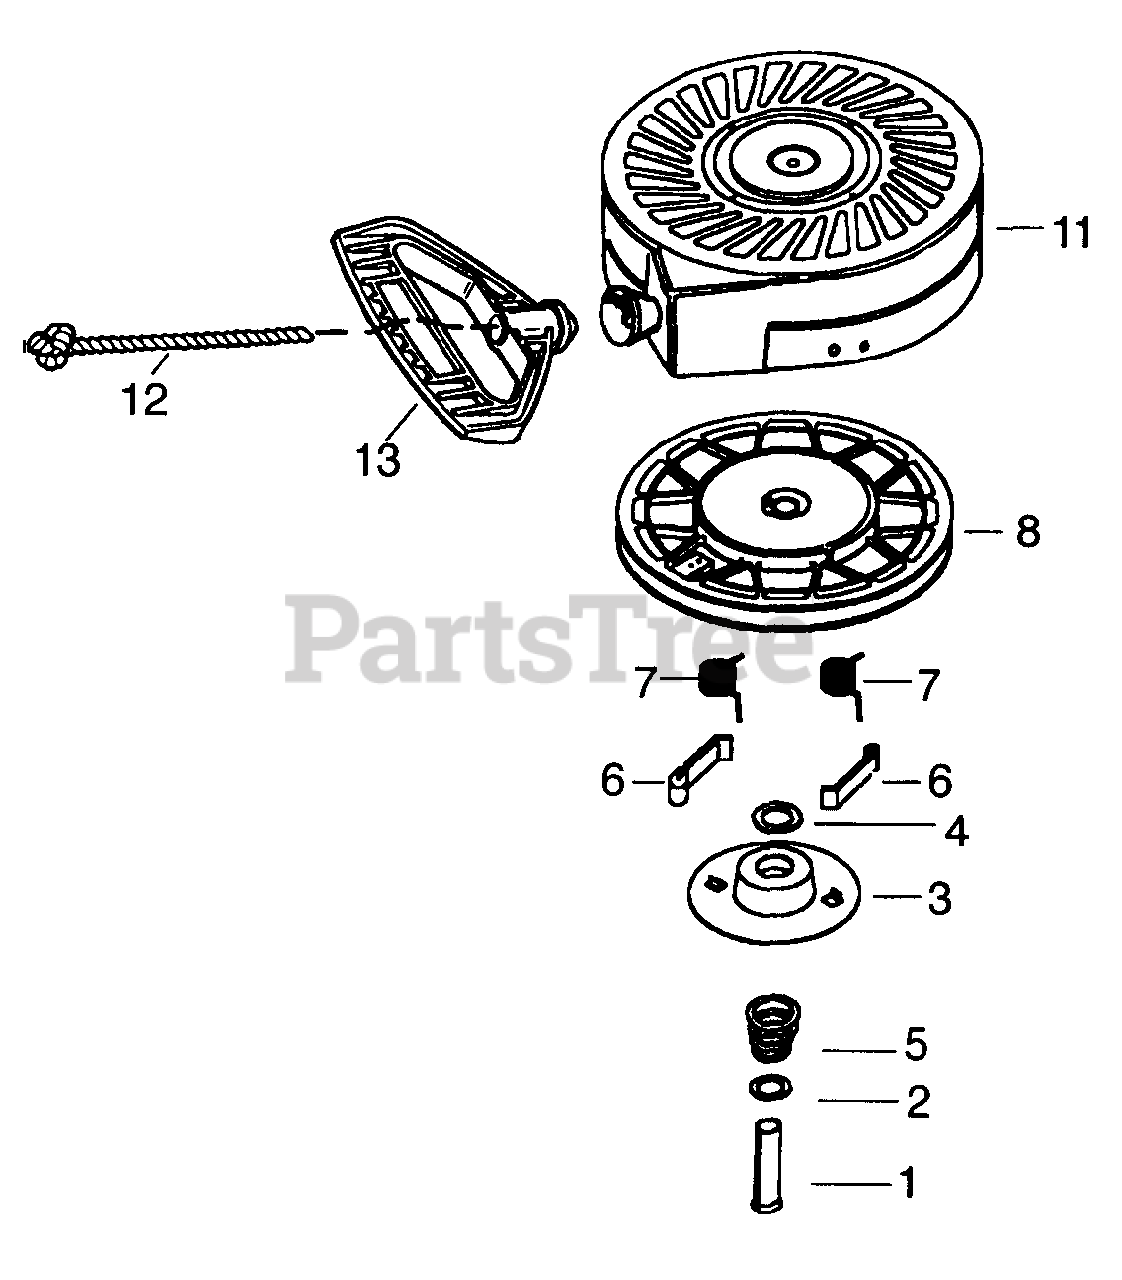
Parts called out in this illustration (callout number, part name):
1	Spring Pin
5	Brake Spring
6	Starter Dog
7	Dog Spring
8	Pulley & Rewind Spring Assy
11	Starter Housing Assy
12	Starter Rope
13	Mitten Grip Handle
